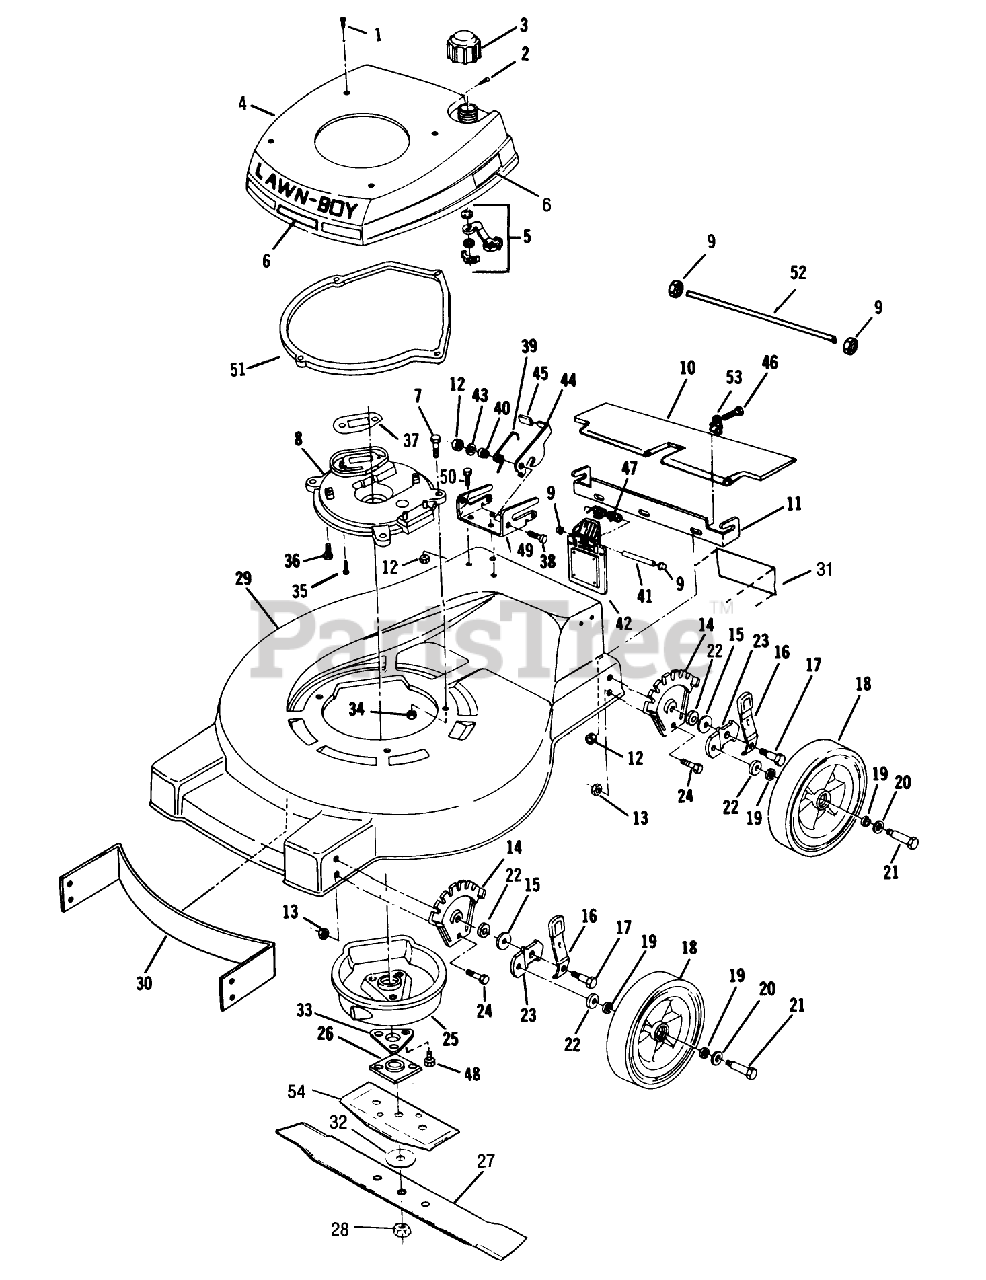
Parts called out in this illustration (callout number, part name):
1	SCREW LAWRENCE
2	SCREW S
3	FUEL CAP & INSERT
7	SCREW-HH
8	PLATE,MUFFLER F
10	T/SHIELD SM&P
12	LOCKNUT E
13	LOCKNUT
16	KNOB&SPRING FORMCO
21	BOLT WHEEL
22	WASHER WROUGHT
26	PLATE AND COLLAR ASM
28	NUT-BLADE
33	SUPPORT F
34	NUT-LOCK F
35	SCREW V
41	ROD ROCK/HDWE
45	KNOB (S&R)
47	SPRING ASOC
